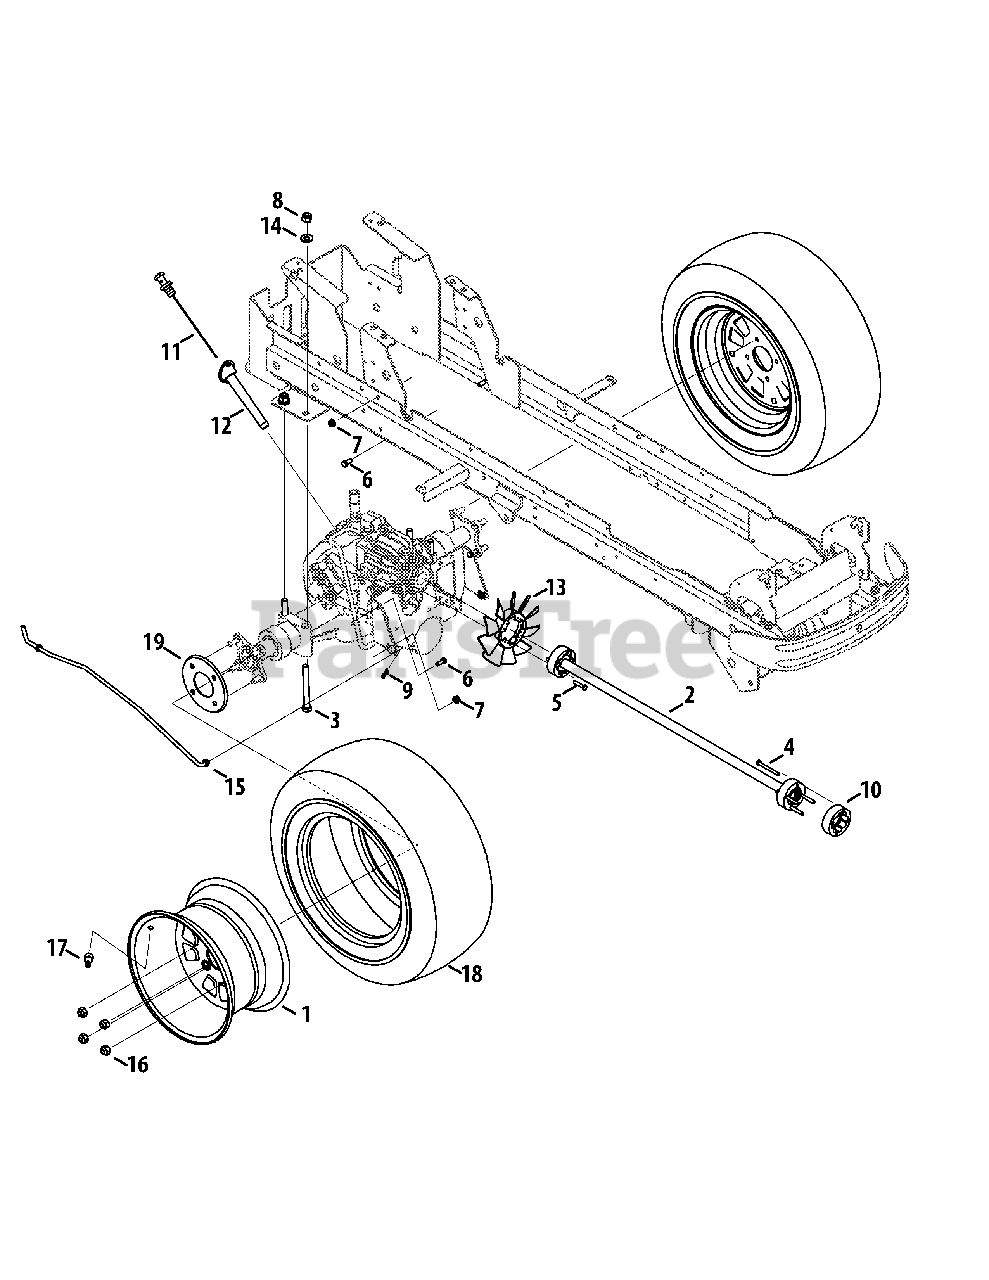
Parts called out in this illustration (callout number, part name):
1	Rim Assembly, 12.0 x 7.0
2	Shaft Assembly, 30.55
3	Hex Screw, 1/2-20 x 4.50
4	Hex Screw, 1/4-20 x 2.50
5	Hex Screw, 1/4-20 x 1.25
6	Hex Screw, 5/16-18 x .75
7	Flange Lock Nut, 5/16-18
8	Hex Lock Nut, 1/2-20
9	Bow-Tie Cotter Pin, 72
10	Drive Shaft Adapter
11	Transaxle Dipstick
12	Dipstick Holder
13	Pump Fan, 7.0
14	Flat Washer, .531 x 1.062 x .134
15	Hydro Relief Lever
16	Lug Nut, 7/16-14
17	Tubeless Air Valve
18	Tire, 23.0 x 10.5 x 12
